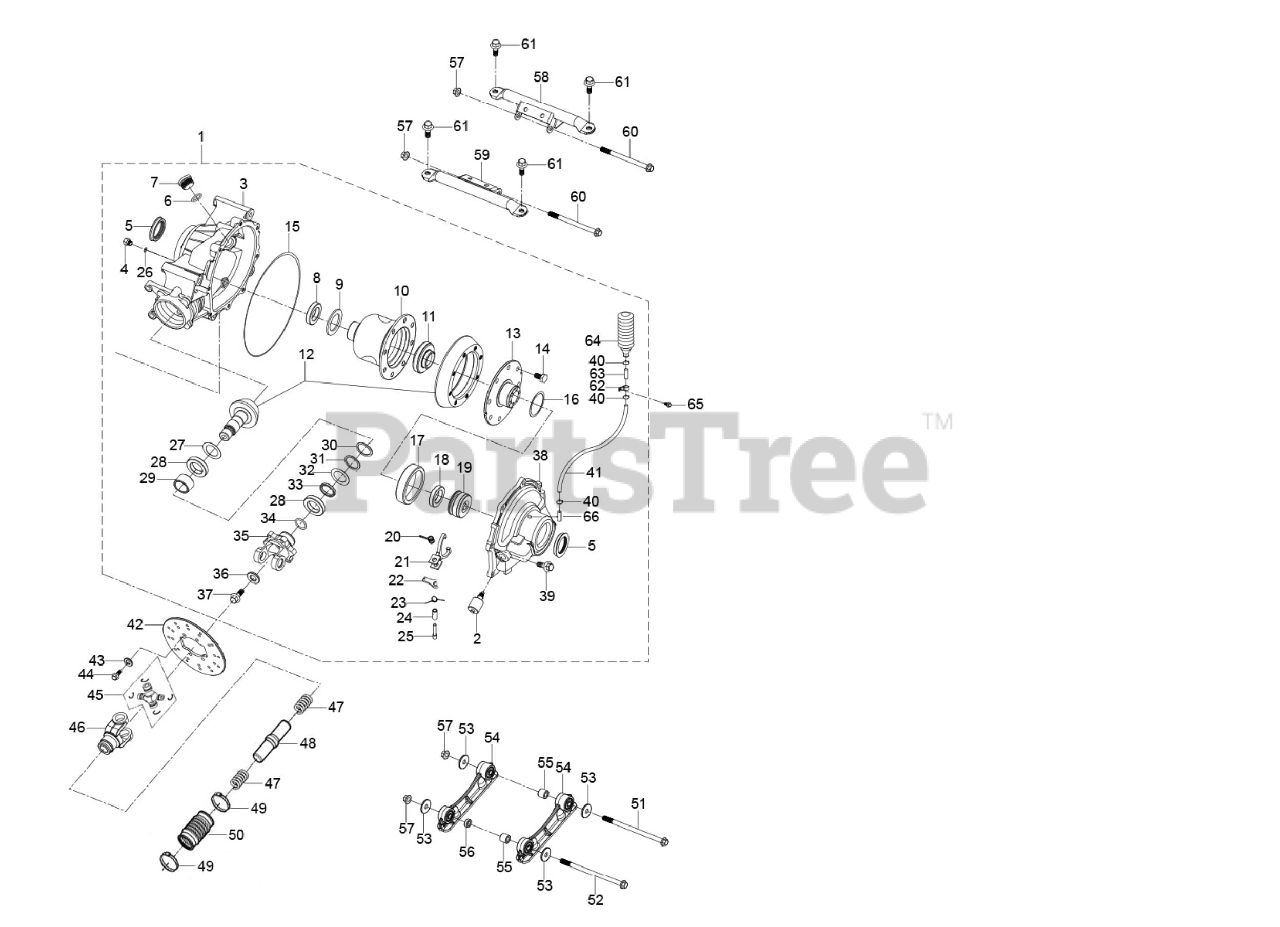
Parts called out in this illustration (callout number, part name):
1	REAR DIFFERENTTIAL ASSEMBLY
2	GEAR MOTOR
3	GEARCASE RH
4	DRAIN PLUG
5	SEAL 35x52x7
6	O-RING 23x3
7	OIL FILL PLUG
8	BEARING - ROLLER BALL 32008
9	SPACER 40.5x57x0.1
10	DIFFERENTIAL CASE
13	SEAT SIDE GEAR
14	BOLT HExAGON FLANGE HEAD M10x1.25-20
15	O-RING 12x192
16	SPACER 50.5x60x0.1
17	BEARING CONE
18	BEARING ROLLER BALL 32010
19	DRIVE CLUTCH
20	SPRING TORSION II
21	SHAFT FORK
22	LIMIT STOP FORK
23	SPRING - TORSION ?
25	BOLT STOPPER
26	O-RING 8x1
27	SPACER 30.6x46x0.1
28	BEARING ROLLER BALL 32206
29	TUBE 30.5x38x15
30	SEAL 40x72x7
31	WASHER - FLAT 30.5x38x2
32	SPACER 30.6x46x0.1
33	TUBE 30.5x38x6.4
34	O-RING 3x24
35	YOKE
37	BOLT HExAGON FLANGE HEAD M12x1.5-30
38	COVER GEARCASE
39	Flange bolt M8x25
40	Spring Clamp E
41	FUEL LINE
42	DISC BRAKE
43	Spring Washer-8
44	Hexagon Flange Bolt M8x20
45	Criss-CrossShaft
47	Rear axle Spring B
49	NARROW BAND CLAMP
50	NARROW BAND CLAMP
51	BOLT HExAGON FLANGE HEAD M10x1.25-200
52	BOLT HExAGON FLANGE HEAD M10x1.25-195
53	WASHER 10x35x3
54	STRAP DIFFERENTIAL-REAR SEAT
55	TUBE 10.5x20x18
56	TUBE 10.5x20x7.5
57	LOCK NUT M10x1.25
58	REAR DIFFERENTIAL SHELF KIT- REAR
59	REAR DIFFERENTIAL SHELF KIT - FRONT
60	BOLT HExAGON FLANGE HEAD M10x1.25-115
61	Flange bolt M8x25
62	Pipe Clamp ?
65	Hexagon Flange Bolt M6x16
